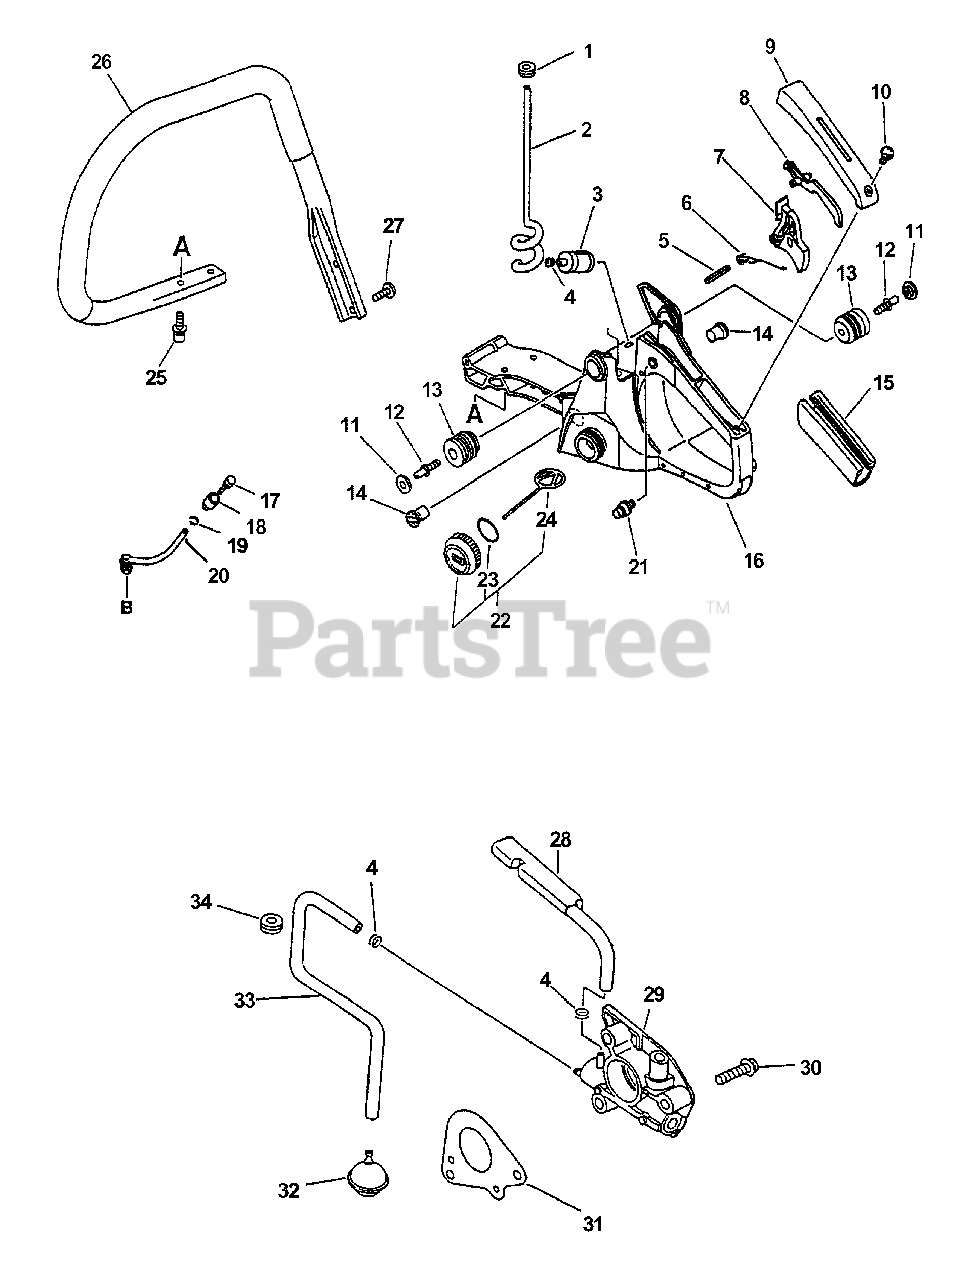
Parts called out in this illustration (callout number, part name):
2	PIPE, FUEL - SPIRAL
3	FILTER, FUEL
4	CLIP - 6.5
5	PIN - SPRING -- 4X30
6	SPRING, TRIGGER
7	TRIGGER, THROTTLE
8	LEVER, TRIGGER LOCKOUT
9	COVER, HANDLE
10	SCREW - 4X14
11	CAP, CUSHION
15	GRIP, HANDLE
16	HANDLE ASSY - REAR
17	VENT, FUEL TANK
18	COVER, VENT
19	CLIP - 6.5
20	PIPE - VENT
21	LATCH, THROTTLE
22	CAP ASSY - ORANGE
23	O-RING - 22
24	CONNECTOR, CAP
25	SCREW - 5X16 -- TAPPING
26	HANDLE - FRONT
27	SCREW - 5X20 -- TAPPING
28	PIPE - OIL
29	AUTO-OILER ASSY
30	SCREW - 4X16
31	SEAL, DUST
32	FILTER, OIL
33	PIPE - OIL
